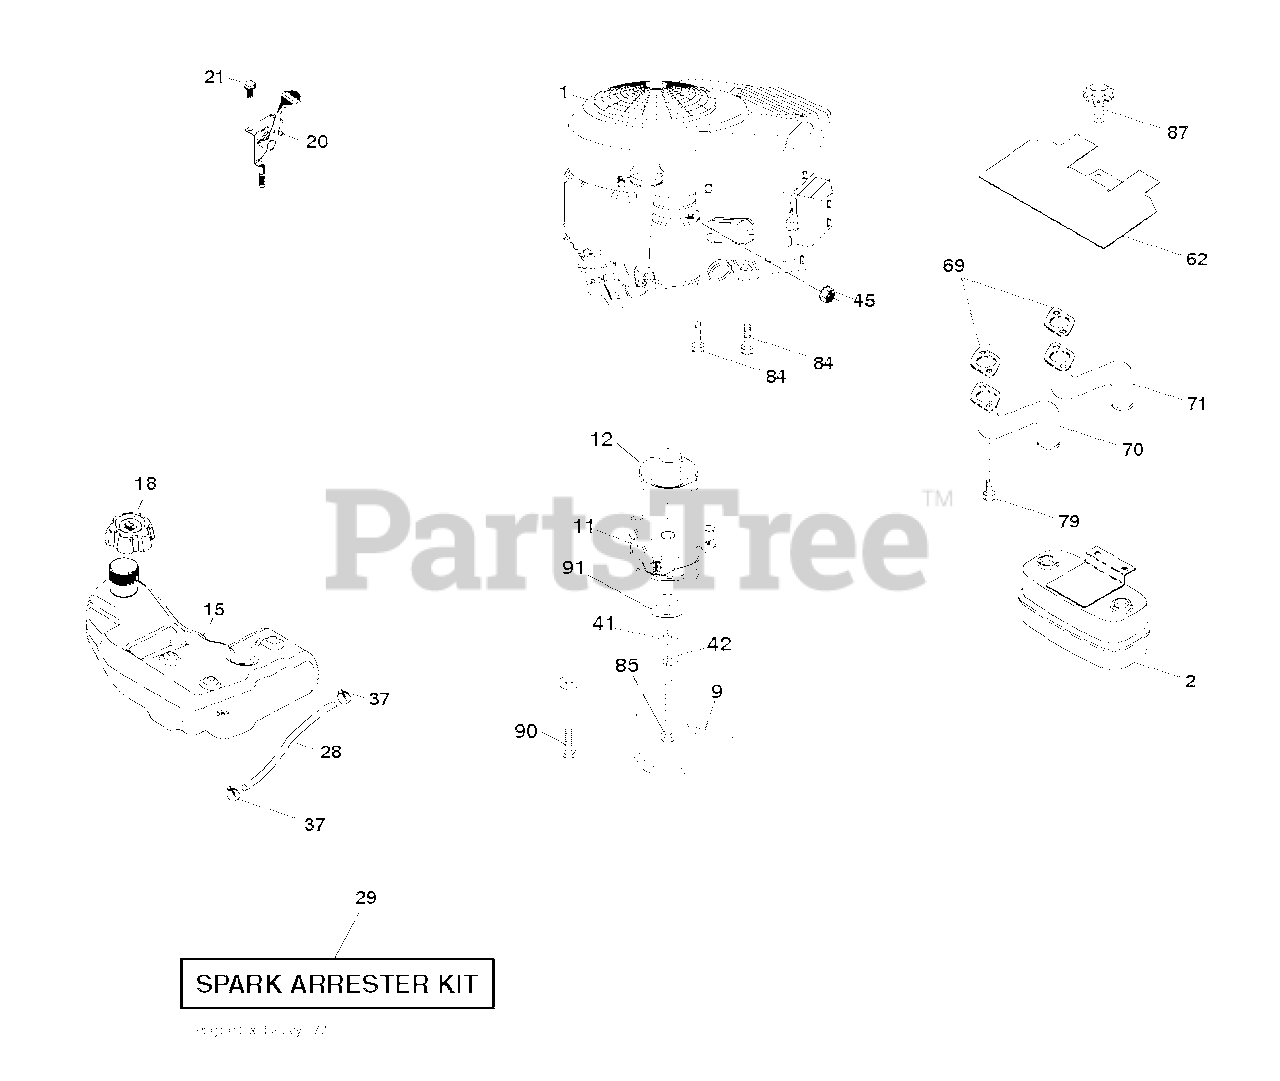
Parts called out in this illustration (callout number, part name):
2	MUFFLER.ASM.TWN.EXTNDED.DFLCTR
9	KEEPER.BELT.ENGINE.4.2
11	CLUTCH MZ ZTR GT.48/54"1.125"
12	PULLEY ENGINE
15	TANK.FUEL.4GAL
18	CAP.FL.R.3'N/CARB.H.CROWN.498
20	CONTROL.TH/CK.COBRA.B&S.TWN.
21	SCREW.#10 X 0.750.BOS
28	REPL BY 532 00 85-43
29	KIT.SPARK ARRESTOR 794945 B&S
37	HOSE CLAMP
42	LOCKWASHER
45	NUT
62	SHIELD.HEAT.MUFFLER
69	GASKET.MUFFLER
70	RP.EXHAUST.TUBE.LH.BS/TWIN
71	EXHAUST.TUBE.RH.BS/TWIN
79	SCREW.SOCKET.HEAD.5/16-18
84	SCREW.3/8-16
85	BOLT HEX 7/16-20 X 3.75 GR. 5
87	BOLT, 5/16-18 X 1 3/4
90	SCREW 3/8-16X1
91	BUSHING.1.375OD
